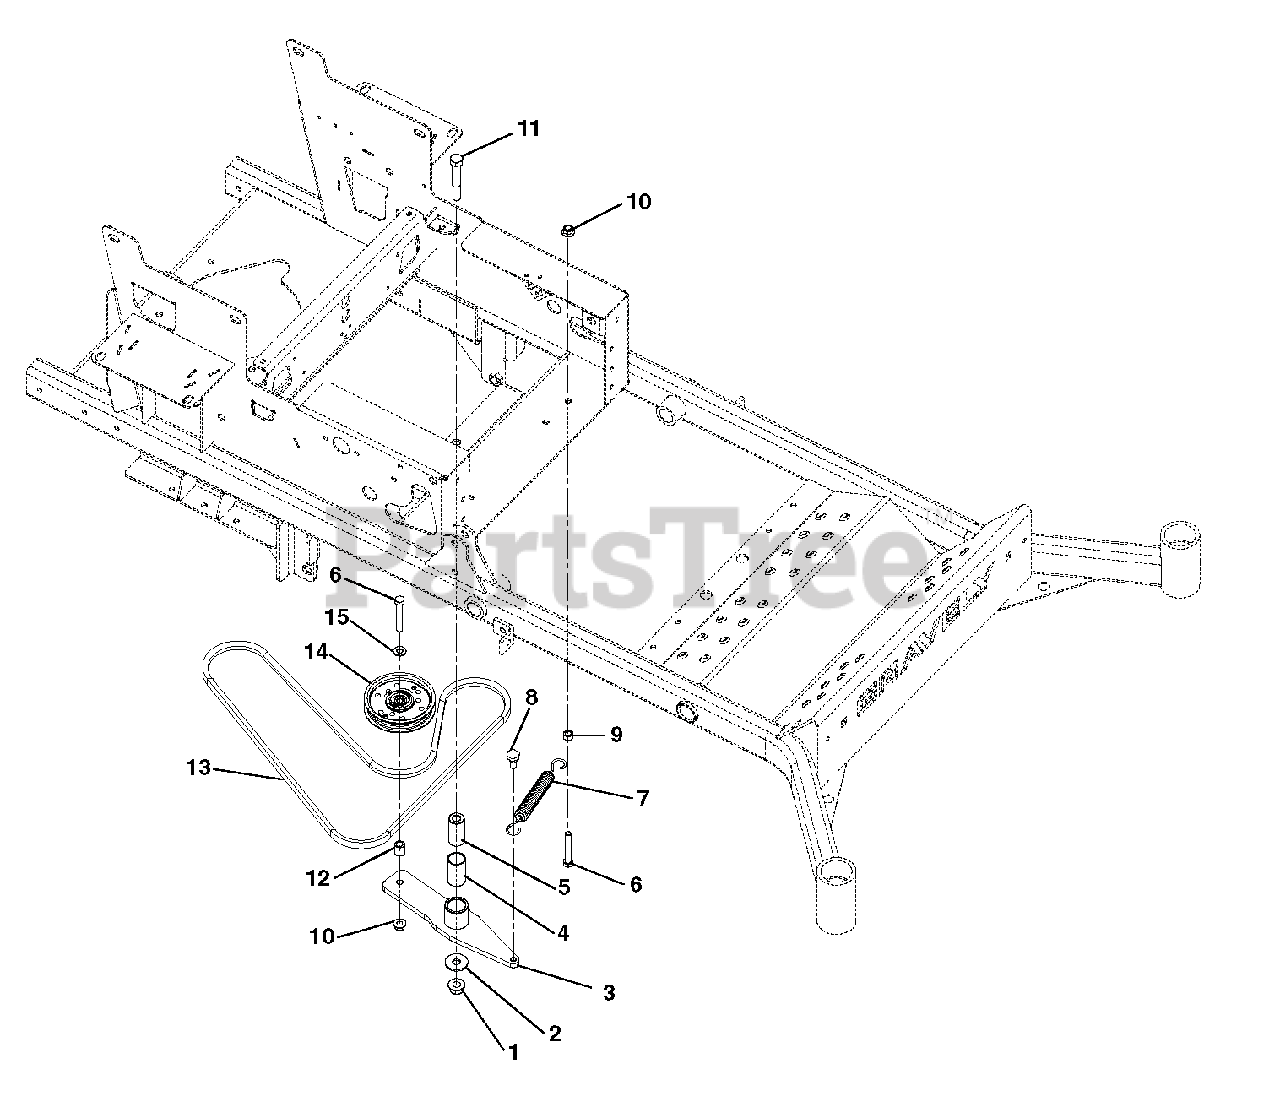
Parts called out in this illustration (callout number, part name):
1	@NUT-LK-NYL-FLG .50-13 YWZC
2	WSHR-FL-STL.511X1.441X.125 YWZ
3	HYDRO DRIVE IDLER ARM WMT -BLK
4	BSHG, 1.00 X 1.125 X 1.937
5	BSHG, SPCR .502X.997X2.03 PM
6	@BLT-HEX .38-16X2.50 GR5 YWZC
7	SPRING, EXTENSION
8	BLT,SHLDR EP .38-16X.30 HEX YZ
9	@NUT-HEX .38-16 YWZC
10	@NUT-LK-NYL-FLG .38-16 YWZC
11	@BLT-HEX .50-13X3.25 GR5 YWZC
12	BSHG-SLV .407X.625X.750 PL
13	V-BELT, A-COGGED
14	IDLER-FLAT 4.00 X .38 NWHAMSHR
15	@WSHR-FL-STL.406X.812X.065 YWZ
